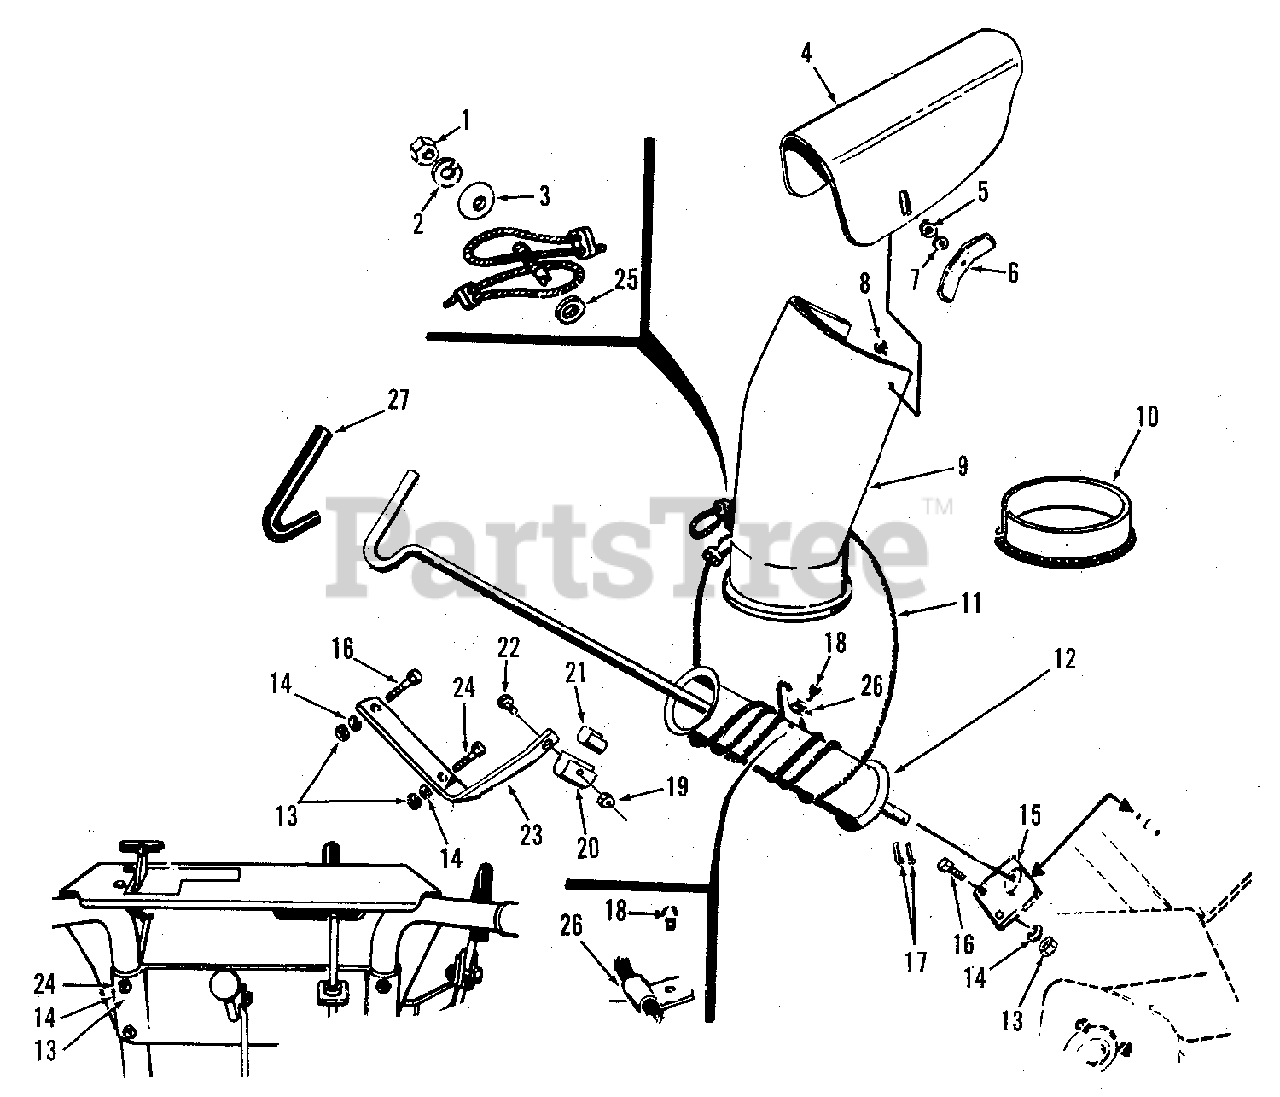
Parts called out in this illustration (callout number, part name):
1	NUT, Full Hex, 5/16-18
2	WASHER, Lock, 5/16"
4	EXTENSION, Spout
5	WASHER, Lock, 3/8" Shakeproof
7	WASHER, Flat, 3/8
8	BOLT, Carriage
9	SPOUT, Assembly
11	CABLE ASSEMBLY
12	ROD, Spout Control
13	NUT, Full Hex, 1/4-20
14	WASHER, Lock, 1/4
16	SCREW, Hex Cap, 1/4-20 x 5/8
17	PIN, Cotter, 1/8 x 3/4
18	SCREW, Taptite, 1/4-20 x 3/8
19	NUT, Full Hex Lock, 5/16-18
21	LINER, Guide
22	SCREW, Hex Cap, 5/16-18 x 1-1/4
23	SUPPORT, Bracket
24	SCREW, Hex Cap, 1/4-20 x 1-3/4
25	WASHER, Flat, 1/4
27	HANDLE, Grip
